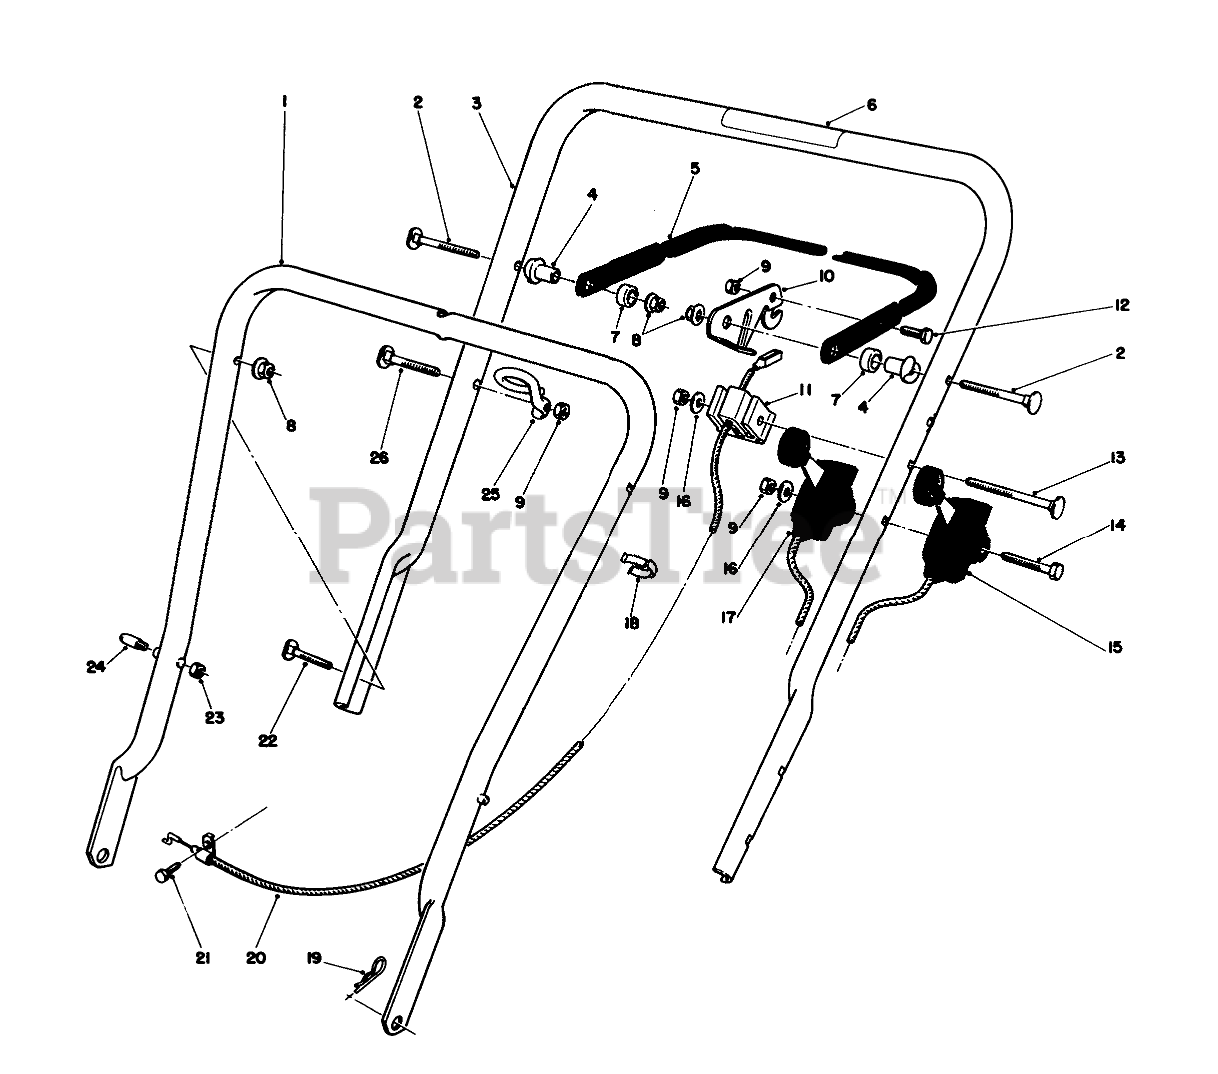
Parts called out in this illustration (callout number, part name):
1	LOWER HANDLE ASM
2	5/16-18 X 2 HNDLE SCREW
3	Handle-Upper (Incl. Ref. #6)
4	SPACER-SUPPORT
5	Bar-Control
6	Decal-Danger
7	SPACER-NYLON
8	NUT-LOCK, NI
9	NUT-LOCK, NI
10	LEVER-CONTROL
11	SUPPORT-CABLE
12	SCREW-HH
13	Screw-Handle
14	SCREW-HH
15	Control-Traction (Bend Type #3)(Sheath Lg. 46")(WireLg. 1-1/4")
16	WASHER-FLAT
17	SERVICE THROTTLE CONTRO
18	BOWDEN CLIP
19	PIN-COTTER, HAIR
20	BRAKE CABLE
21	SCREW-HH
22	SCREW
23	NUT-LOCK, NI
24	HANDLE PIN
25	Guide
26	HANDLE SCREW
